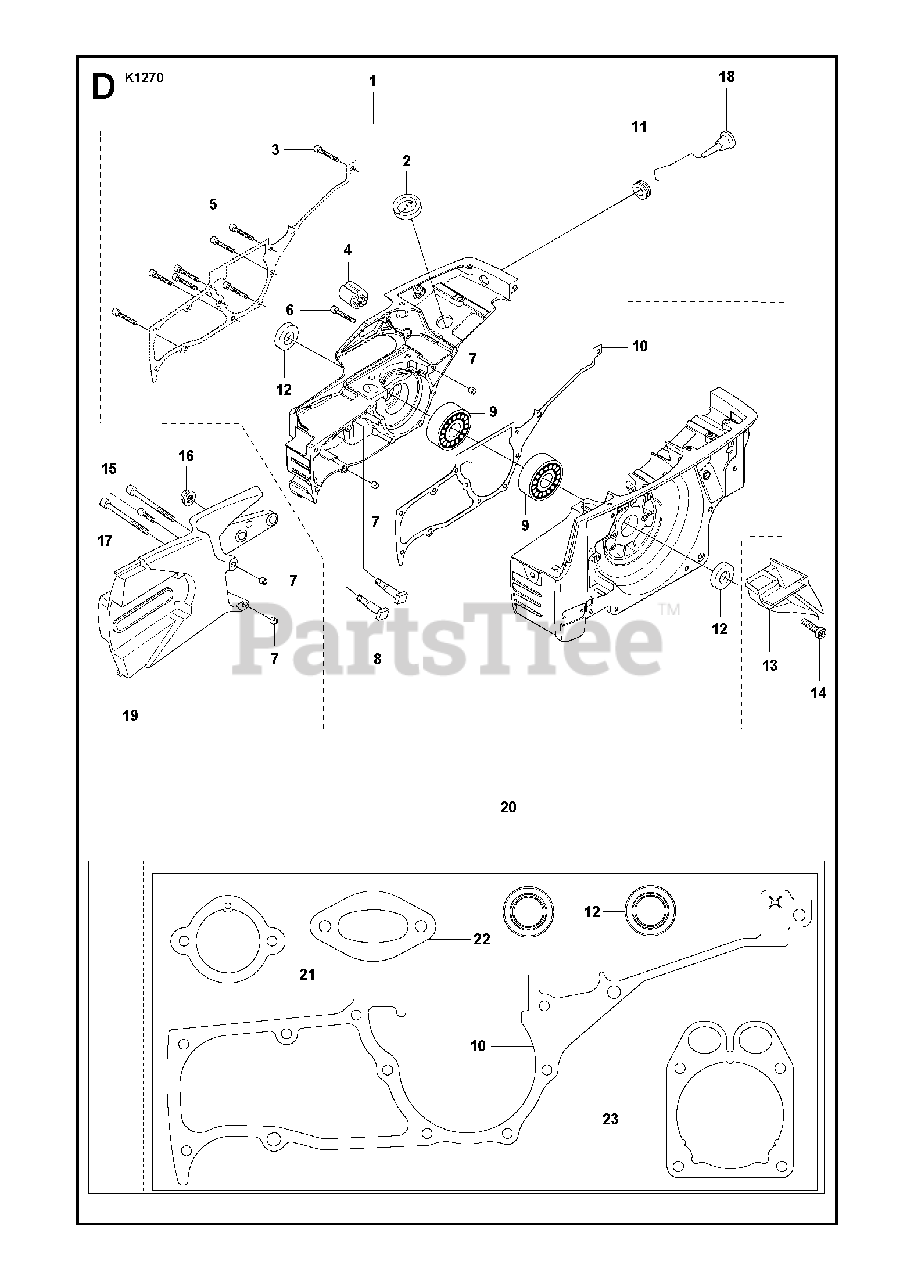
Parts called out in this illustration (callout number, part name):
1	CRANKCASE ASSYIncl. 2-11
3	SCREW ITXSCM
4	ANTIVIBRATION ELEMENT
5	SCREW ITXSCM
6	SCREW ITXSCM
7	GUIDE BUSHING
9	BALL BEARING
12	SEALING RING
14	SCREW ITXSCM
15	SCREW ITXSCM
17	SCREW ITXSCM
19	CUTTER ARM
20	GASKET KITIncl. 10, 12 21 - 23
